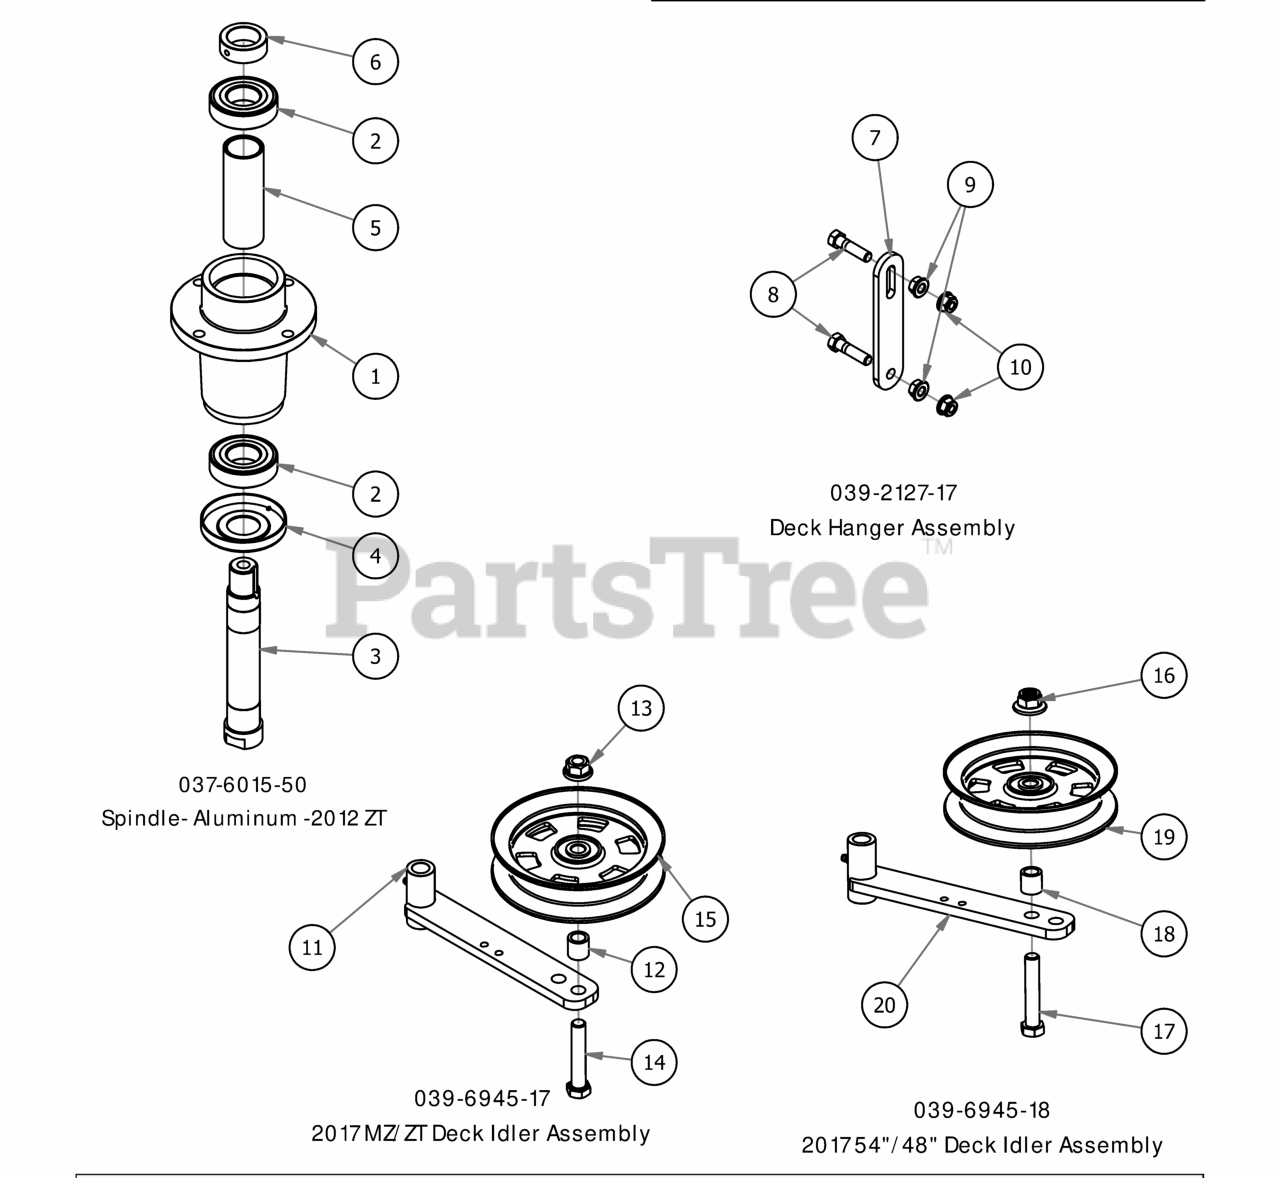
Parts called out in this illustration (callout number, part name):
1	Aluminum Spindle Housing -2010
2	Spindle Bearing, 2004 and up
3	Short Spindle Shaft w/Locking
4	Dust Cover
5	Tube Spacer for Spindle Shaft
6	Collar Spacer - Top of Spindle
7	2017 MZ/ZT Deck Hanger
8	3/8" x 1 1/2" Hex Bolt
9	3/8" Flange Nut
10	3/8" Nylock Flange Nut
11	Deck Idler
12	.51 ID X .75 OD X .75 LGTH SOLID SPACER ZINC
13	1/2-13 NYLON INSERT FLANGE LOCKNUT ZINC
14	1/2-13 X 2-3/4 HEX CAP SCREW (GR.5) ZINC
15	5" Idler Pully
16	1/2-13 Nylon Flange Nut
17	1/2" x 2 3/4" Hex Bolt
18	Spacer 3/4 OD x 1/2 ID x 3\4 Length
19	5" Idler Pully
20	Deck Idler
